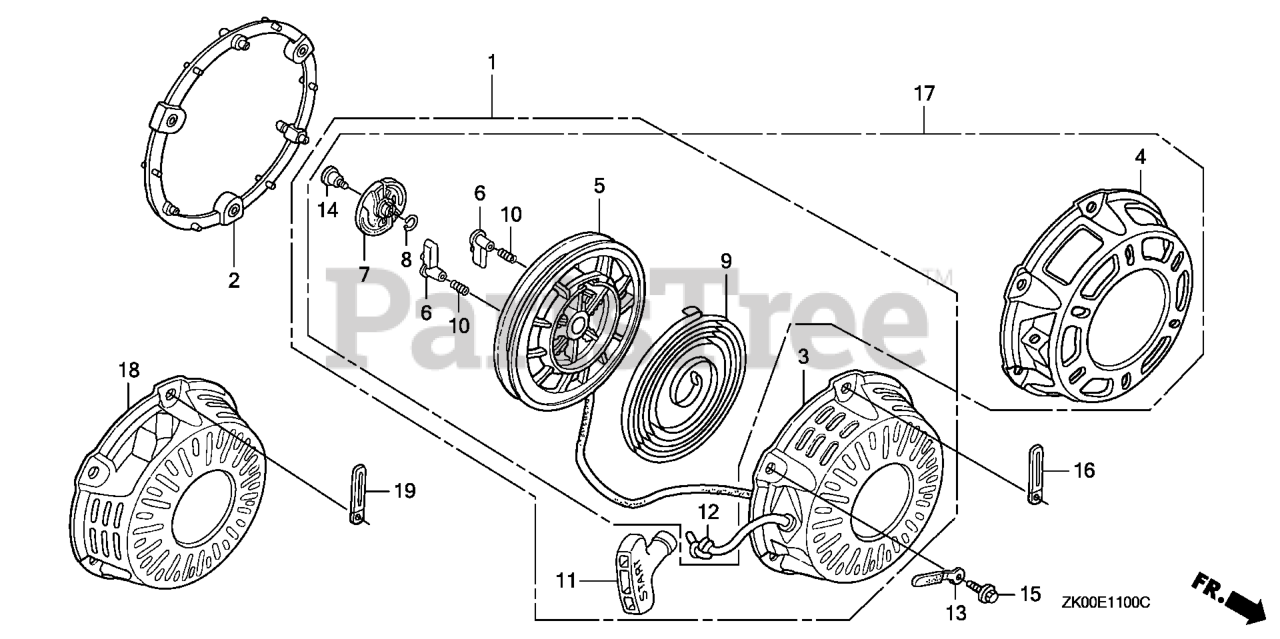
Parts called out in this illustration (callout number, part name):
1	STARTER ASSY., RECOIL *R280* (POWER RED)
1	STARTER ASSY., RECOIL *NH1* (BLACK) (ENGINE NO.)
2	SPACER, RECOIL STARTER MOUNTING *NH1* (BLACK)
2	SPACER, RECOIL STARTER MOUNTING *R280* (POWER RED)
3	CASE, RECOIL STARTER *R280* (Honda Code 7346836). (POWER RED)
3	CASE, RECOIL STARTER *NH1* (Honda Code 4193058). (BLACK)
5	REEL, RECOIL STARTER (NATURAL) (ENGINE NO.)
6	RATCHET, STARTER
7	GUIDE, RATCHET (ENGINE NO.)
8	SPRING, FRICTION (ENGINE NO.)
9	SPRING, RECOIL STARTER
10	SPRING, RETURN (ENGINE NO.)
11	GRIP, STARTER
12	ROPE, RECOIL STARTER (#5X55")
14	SCREW, SETTING (ENGINE NO.)
15	BOLT, FLANGE (6X18)
